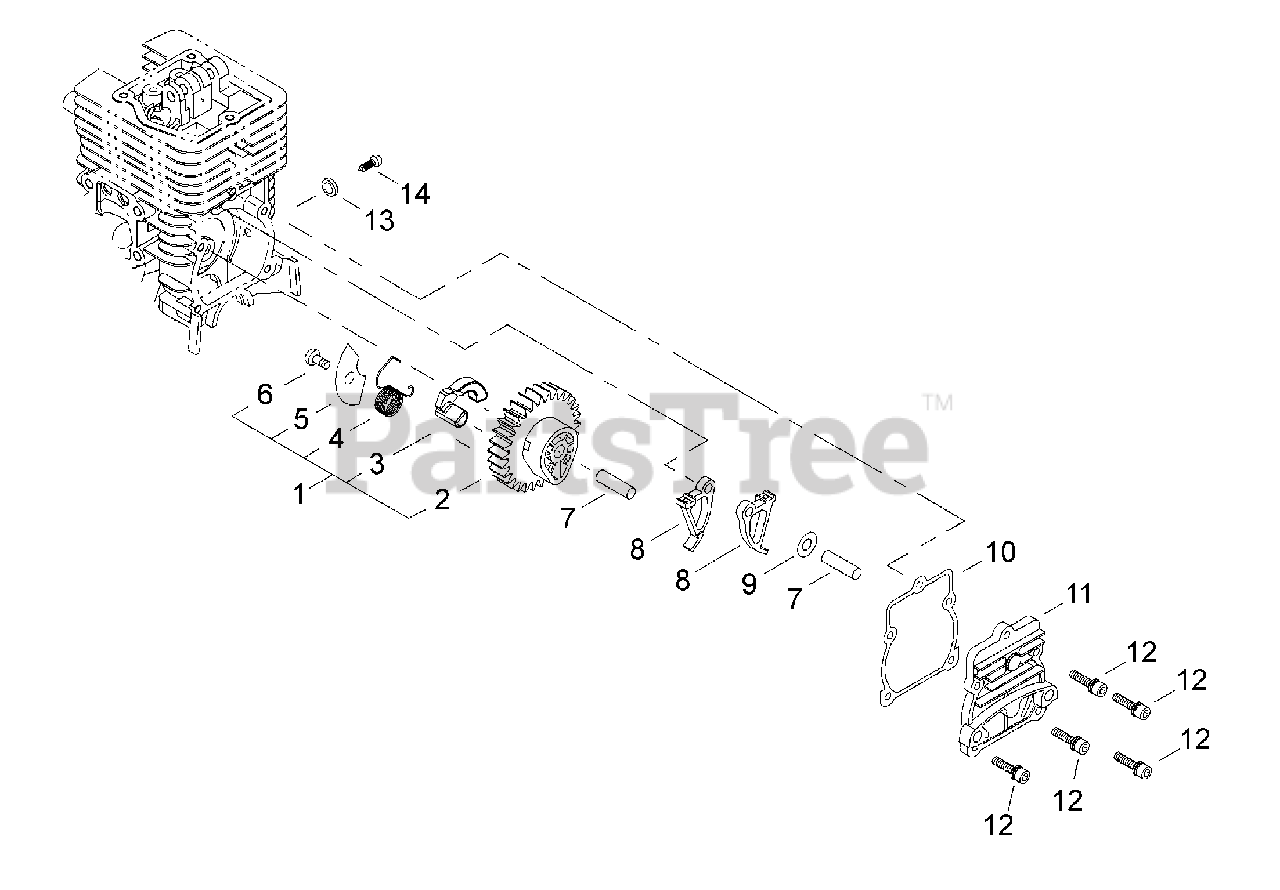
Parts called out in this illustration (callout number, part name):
1	CAM GEAR ASSY
2	GEAR, CAM
3	WEIGHT
4	SPRING
5	COVER, PLATE
6	SCREW - 4X6 -- TAPPING
7	PIN - LOCATING
8	FOLLOWER, CAM
9	WASHER - 5
10	GASKET
11	COVER, CAM GEAR
12	SCREW - 4X14
13	WASHER
14	SCREW - 5
